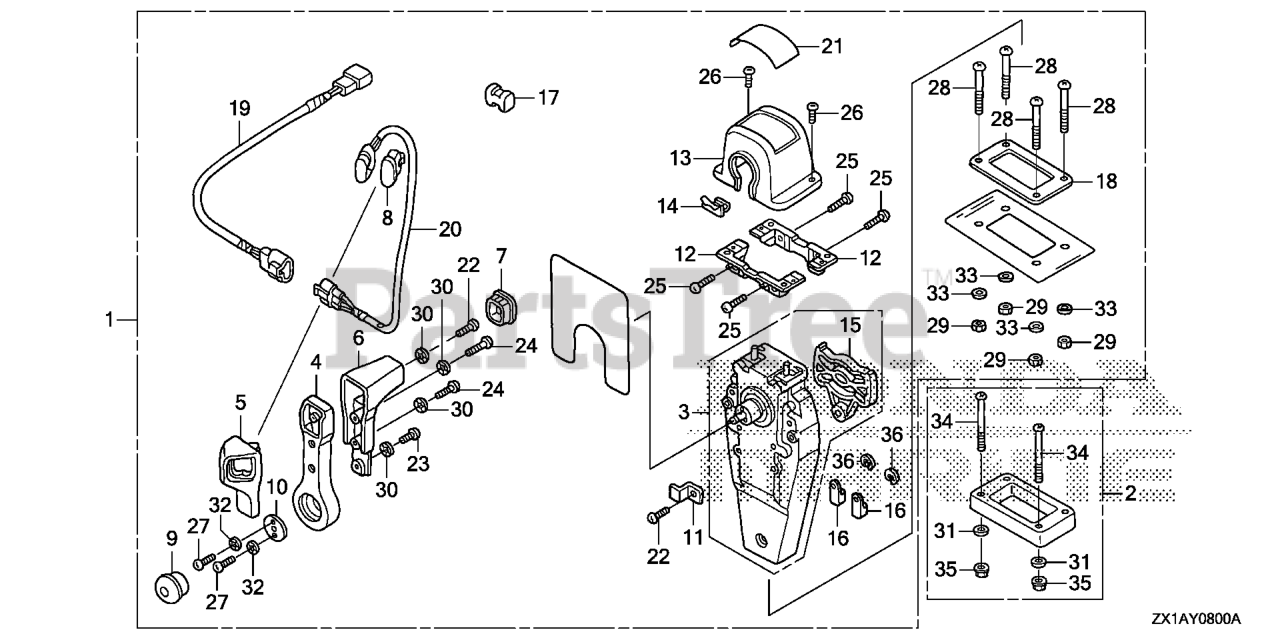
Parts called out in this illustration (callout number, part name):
1	BOX KIT, REMOTE CONTROL (TOP MOUNT SINGLE)(R)
2	SPACER KIT, REMOTE CONTROL BOX (TOP MOUNT SINGLE)
3	HOUSING ASSY., L. (INNER) (TOP MOUNT)
4	HANDLE, REMOTE CONTROL
5	COVER, L. GRIP
6	GRIP, REMOTE CONTROL HANDLE
7	CAP, GRIP
8	CAP, SWITCH
9	BUTTON, THROTTLE
10	PLATE, HANDLE
11	PLATE, CABLE CLAMP
12	BRACKET, REMOTE CONTROL HOUSING
13	HOUSING, REMOTE CONTROL BOX
14	HOUSING, LEAD
15	PLATE, DWELL
16	TERMINAL, CABLE
17	SPACER, CABLE CLAMP
18	GASKET, SINGLE
19	SUB-HARNESS ASSY., POWER TRIM-TILT (A)
20	SWITCH ASSY., POWER TRIM-TILT (A)
21	MARK, REMOTE CONTROL (SINGLE)
22	SCREW, PAN (5X16)
23	SCREW, PAN (5X10)
24	SCREW, PAN (5X20)
25	SCREW, PAN (5X18)
26	SCREW, PAN (4X10)
27	SCREW, PAN (6X18)
28	SCREW, PAN (5X40)
29	NUT, HEX. (5MM)
30	WASHER, LOCK (5MM)
31	WASHER, PLAIN (5MM)
32	WASHER, LOCK (6MM)
33	WASHER, PLAIN (5MM)
34	SCREW, PAN (5X65)
35	NUT, HEX. (5MM)
36	E-RING (6MM)
